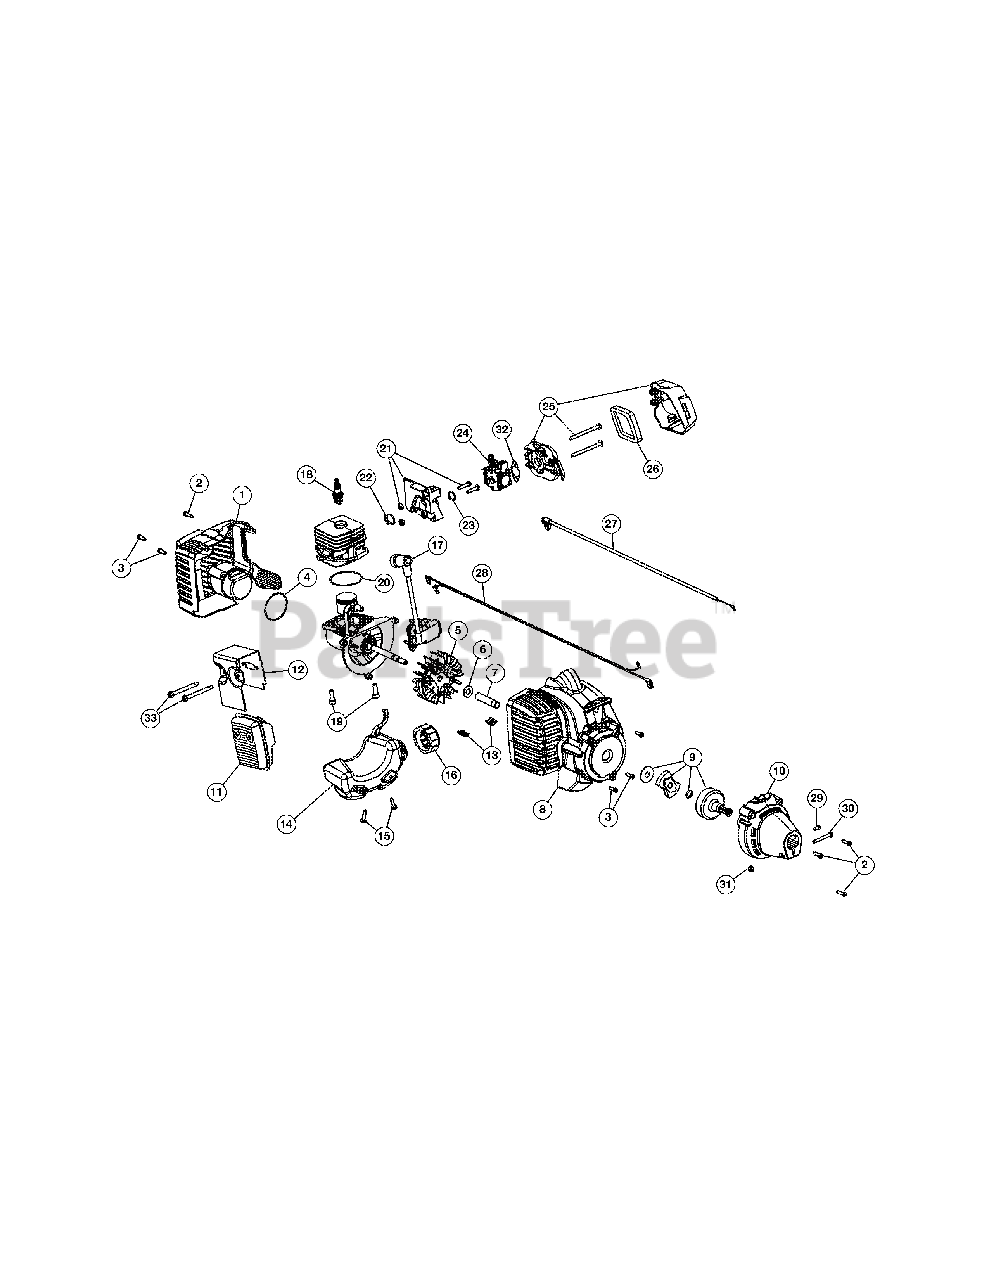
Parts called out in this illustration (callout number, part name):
1	Rear Cover Assembly (Incl Ref No. 2 & 3)
2	Cover Screw
3	Housing Screw
4	O-Ring
5	Flywheel Assembly
6	Washer
7	Spacer
8	Starter Housing (Incl Ref No. 3 & 13)
9	Starter Clutch Assembly
10	Clutch Cover (Incl Ref No. 2)
11	Muffler Assembly (Incl Ref No. 12 & 33)
12	Muffler Gasket
13	U-shaped Nut
14	Fuel Tank Assembly (Incl Ref No. 15 & 16)
15	Tank Screw
16	Fuel Cap
17	Module Assembly
18	Spark Plug
19	Crankcase Bolt
20	Crankcase O-Ring
21	Insulator Assembly (Incl Ref No. 22 & 23)
22	Insulator O-Ring
23	Carburetor O-Ring
24	Carburetor
25	Aircleaner Cover Assembly (Incl Ref No. 26)
26	Aircleaner Filter
27	Throttle Cable
28	Lead Wires
29	Anti-rotation Screw
30	Clamp Screw
31	Clamp Nut
32	Air Cleaner Gasket
33	Muffle Screws
